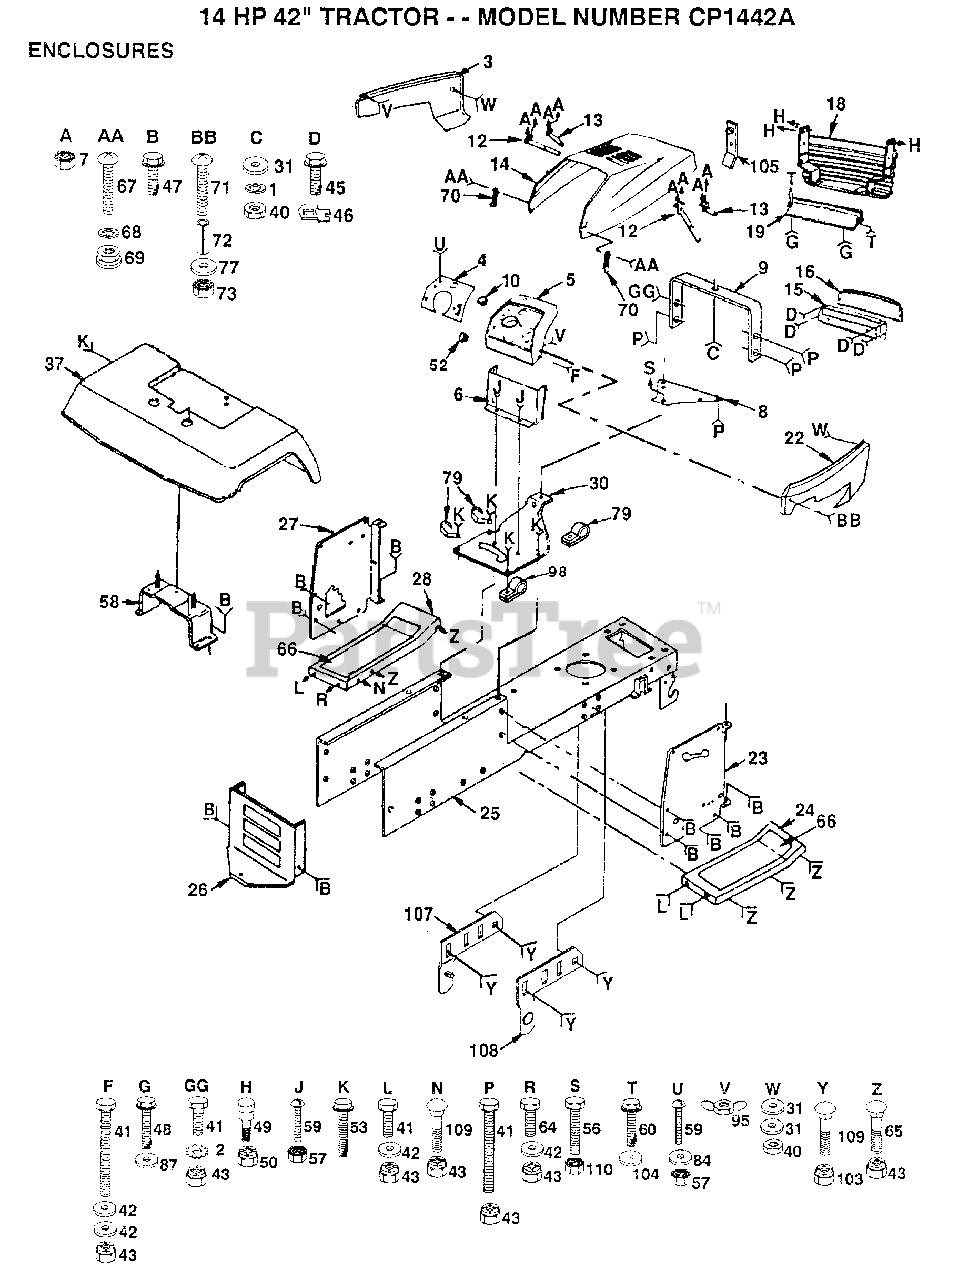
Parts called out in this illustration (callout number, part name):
1	LOCKWASHER
2	LOCKWASHER
3	"PANEL,SIDE LH"
7	NUT
9	SUPPORT ASS'Y
10	PLUG BUTTON T
16	LENS LT
22	"PANEL, SIDE RH"
27	DASH PANEL LH
30	SADDLE.LT.GOOSE
31	WASHER PM
42	WASHER
46	"""J"" FASTENER LT"
47	SCREW
48	SCREW
52	PLUG DOME
53	SCREW LT
56	BOLT
58	BRKT FENDER
59	SCREW
60	SCREW HEX CRT
65	BOLT
66	FOOTREST PAD
67	SCREW
68	LOCKWASHER
70	HOOD LATCH T
71	SCREW
72	SPACER LT
77	WASHER
79	CLIP T
84	WASHER
87	WASHER
98	"CLIP,INSULATOR"
103	NUT
104	WASHER
107	PIVOT BRKT LH
108	PIVOT BRKT RH
